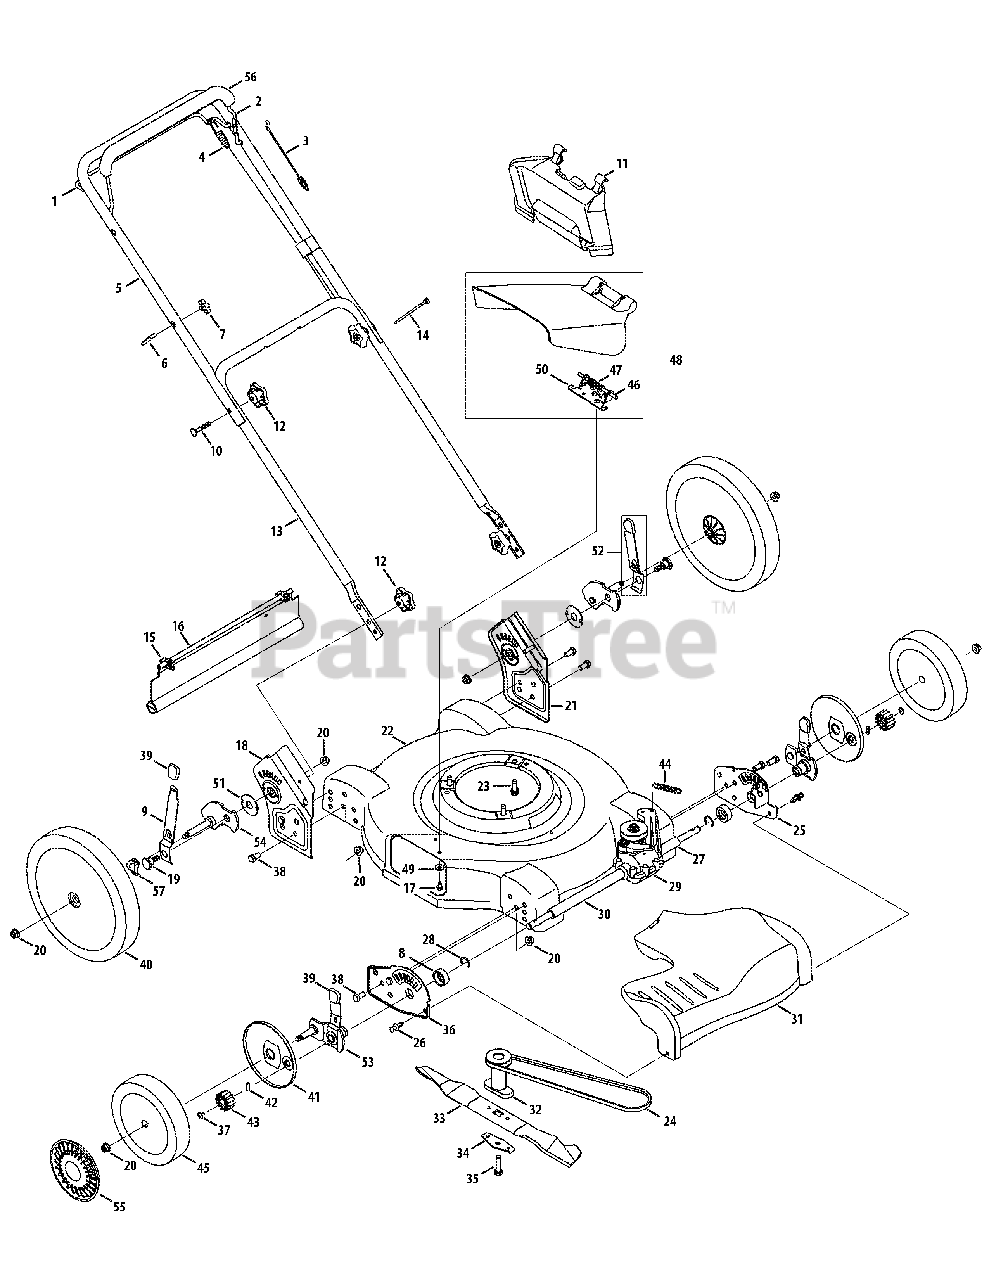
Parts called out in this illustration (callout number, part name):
1	Drive Control
3	Control Cable - 40.75''
4	Drive Control Cable
6	Eye Bolt
7	Wing Nut, 1/4-20
8	Bearing Support Spacer
9	Spring Lever
10	Carriage Bolt, 5/16-18 x 2.0
11	Muliching Baffle
12	Star Knob
14	Cable Tie
15	Hinge Clip
16	Trail Shield
17	Hex Screw, 1/4-20 x .500
19	Shoulder Screw, .625 x .412
20	Lock Nut, 3/8-16
23	Hex Washer Screw, 3/8-16 x 1.0
24	V-Belt, 3L x 32.90
26	Rivet
27	Sleeve Spacer, .550 ID x 2.22
28	Retainer Ring
29	Transmission Assembly Complete
30	Sleeve Spacer, .550 ID x 8.51
31	Transmission Cover
32	Blade Adapter
33	22'' Mulching Blade
34	Blade Bell Support
35	Hex Cap Screw, 3/8-24 x 1.5
37	Screw, 1/4-20 x .390
38	Hex Cap Screw, 3/8-16 x .75
39	Adjustment Knob
40	Rear Wheel, 12 x 2.125 Zag
41	Wheel Dust Cover
42	Pin
43	Spur Gear 14T - RH
43	Spur Gear 14T - LH
44	Extension Spring, .47 OD x 2.50
45	Front Wheel, 8 x 2.125, Zag
46	Hinge Pin
47	Torsion Spring
48	Side Discharge Assembly
49	Bell Washer, .265 ID x .75 OD
50	Deflector Chute Adapter
51	Thrust Bearing
52	Rear Height Adjustment Lever Assembly
53	Front Lever Assembly
54	Rear Pivot Arm Assembly - LH
54	Rear Pivot Arm Assembly - RH
55	Hub Cap
56	Deluxe Bail Cover
57	Washer, Spring .500 x 1.00x x.022
